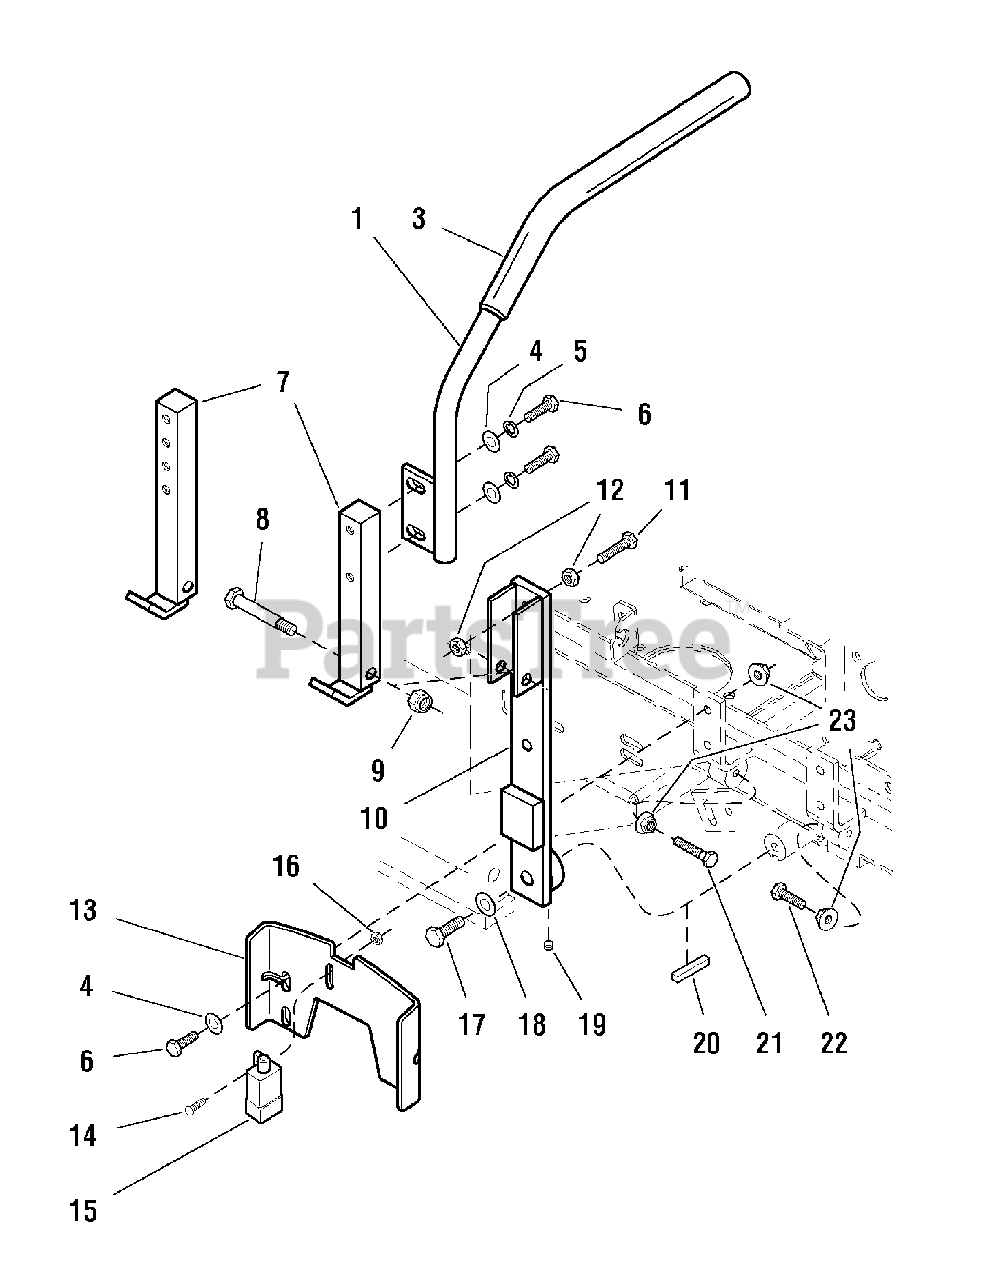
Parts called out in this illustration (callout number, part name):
1	MOTION CONTROL LEVER-RH
4	WASHER, 5/16
5	WASHER, Lock, 5/16
6	CAPSCREW, Hex Hd, 5/16-18 x 3/4
7	CONTROL LEVER BASE (2 holes, S/N: 1000 & below)
8	CAPSCREW, Hex Hd, 3/8-16 x 2
9	NUT, Hex, Nylon Lock, 3/8-16
10	CONTROL LEVER MOUNT
11	CAPSCREW, Hex Hd, 5/16-18 x 1
12	NUT, Hex, 5/16-18
13	NEUTRAL LOCK PLATE
14	SCREW, #10-24 x 1
15	SWITCH (see electrical schematic)
16	NUT, Hex, #10-24
17	CAPSCREW, Hex Hd, 3/8-16 x 1-1/4 w/ patch
18	WASHER, 3/8
19	SET SCREW, 5/16-18 x 1/4 w/ patch
20	KEY, 1/4" x 1
21	CAPSCREW, Hex Hd, 5/16-18 x 1-3/4
22	CAPSCREW, Hex Hd, 5/16-18 x 1-1/4
23	NUT, Hex, Serrated Flange, 5/16-18
